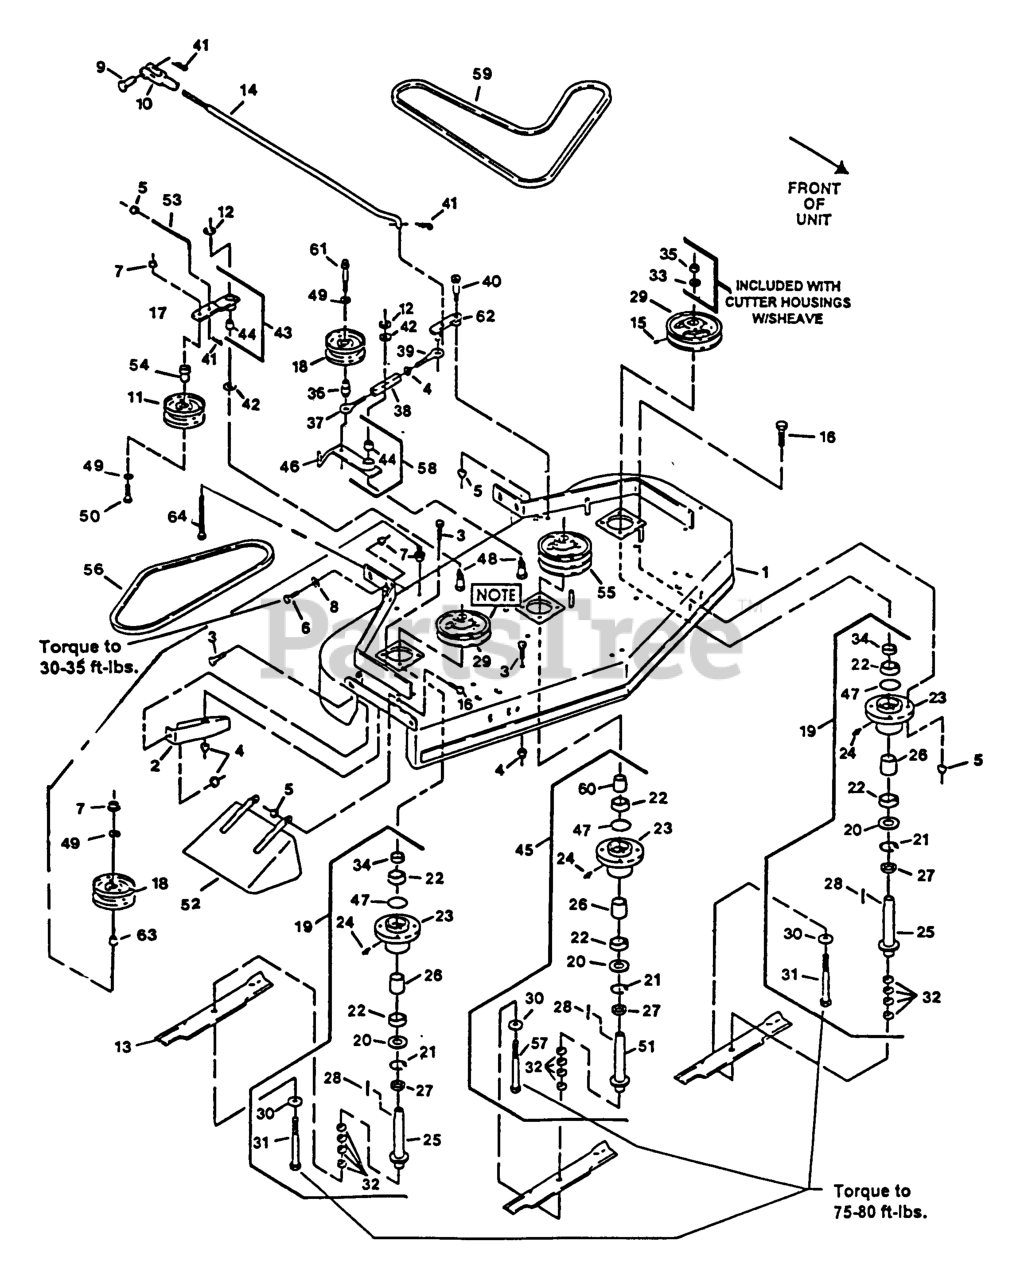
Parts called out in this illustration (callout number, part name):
2	BAFFLE-DOGLEG
9	PIN-CLEVIS
10	YOKE-ADJUSTABLE
11	IDLER,PULLEY
15	SCREW-SET
17	Arm Weldmt, Rh
19	ASM,HOUSING CUTTER
20	SEAL,DUST
21	RING,SNAP WLDS N5000-244
22	BEARING,HD SPINDLE
23	HOUSING,CUTTER
26	SPACER,BRG/BRG
27	SPACER,BEARING &SPINDLE
30	WASHER-SPRING
31	SCREW-CAP, HH
33	WASHER-RETAINER, SHEAVE
36	BUSHING-ENGAGEMENT
37	EYEBOLT-THREAD, LH
38	BODY-TURNBUCKLE
39	EYEBOLT-THREAD, RH
40	BOLT,SHLDR KSKH
41	PIN-COTTER
42	WASHER-SPINDLE
43	ARM WLDMNT W/BUSHING
44	BEARING,POWDERED METAL
52	Chute
53	LINKAGE
54	BUSHING-IDLER
56	BELT,FRONT DECK
57	SCRW,CAP HH 5/8-18X8.5
59	BELT,BLADE DRIVE 48
60	SPACER,BEARING/SHEAVE
63	BUSHING,IDLER
64	BOLT,TAP HH3/8-16X2-1/4
